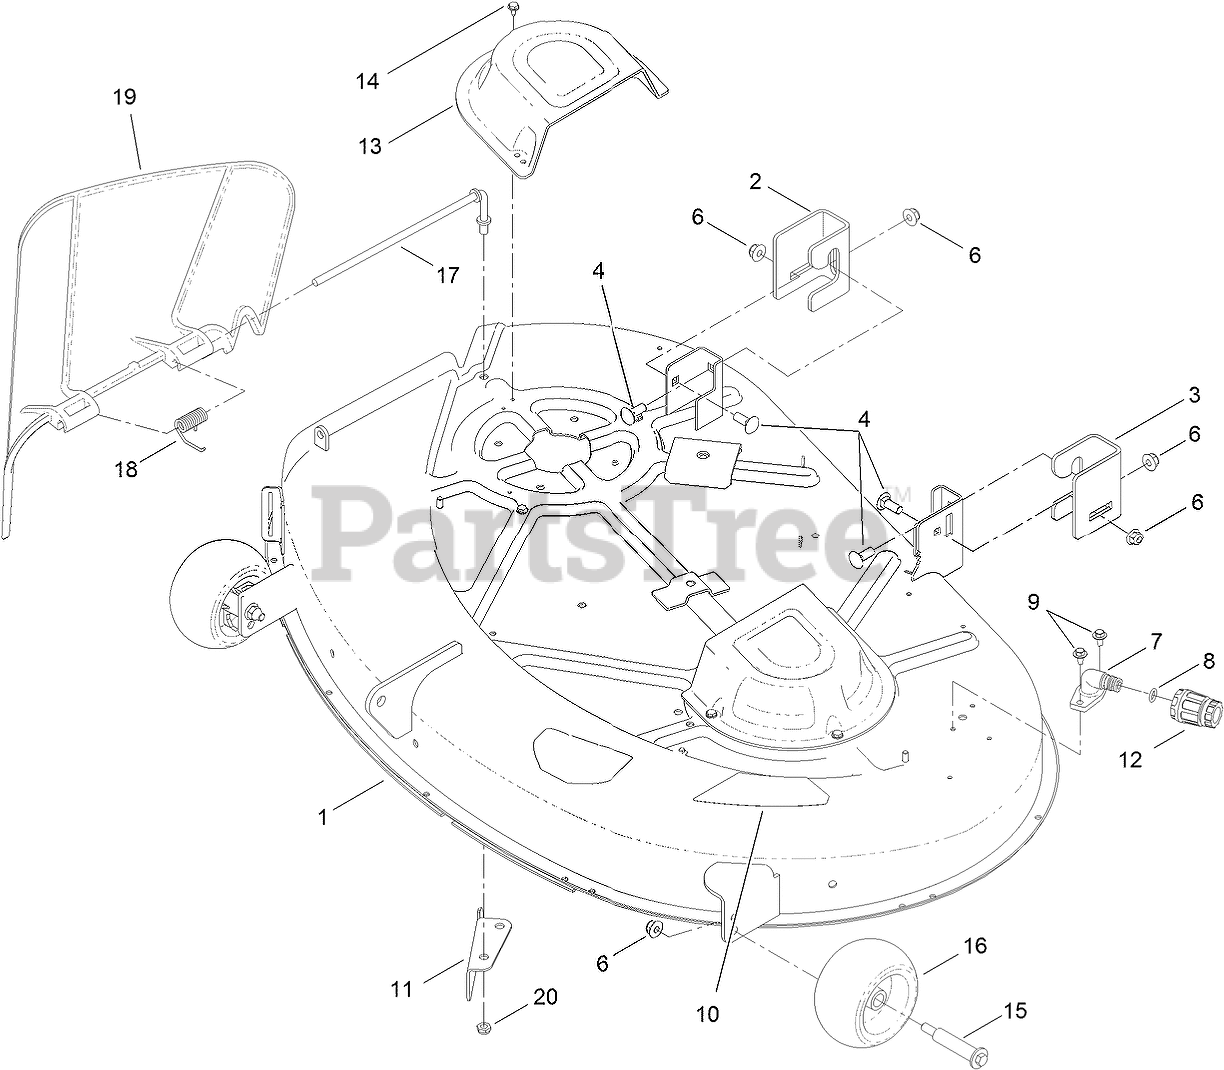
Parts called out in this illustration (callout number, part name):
1	42 INCH DECK AND DECAL ASM
2	BRACKET-HANGER, RH
3	BRACKET-HANGER, LH
4	BOLT-CARR
6	NUT-HF, NI
7	FITTING-WASHOUT
8	O-RING
9	SCREW-HHFTF
11	BAFFLE-CUTOFF
12	CONNECTOR-HOSE
13	COVER-BELT
14	SCREW-HWHTF
15	BOLT-SHOULDER
16	ROLLER-SCALP, ANTI
17	ROD-PIVOT
18	SPRING-TORSION
19	DEFLECTOR
20	NUT-LOCK, NI
